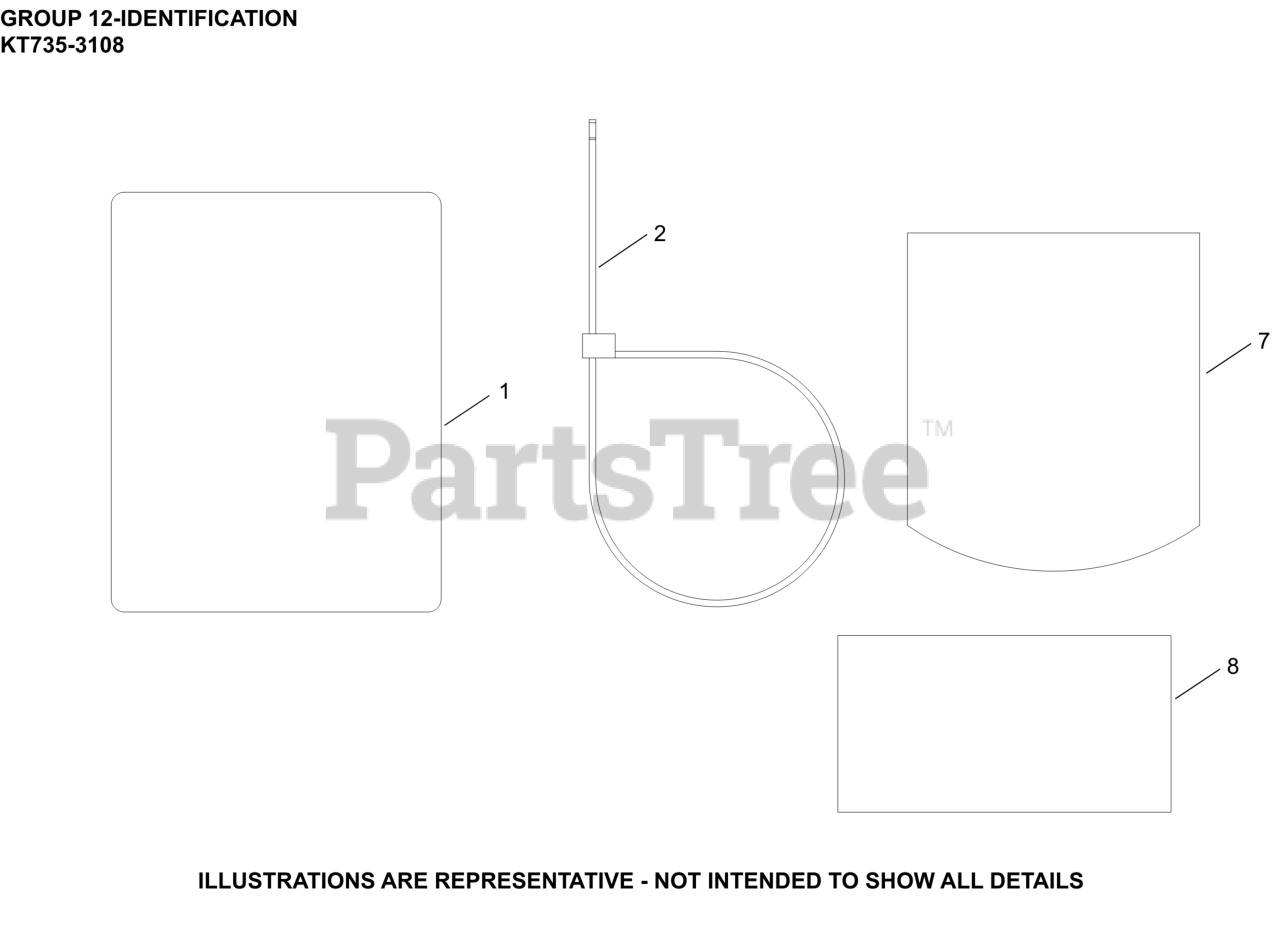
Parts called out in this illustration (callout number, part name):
1	LABEL, CLEAR LAMINATION
7	LABEL, 7000 SERIES KT735 (24 HP,PRO A/F)
8	DECAL, USA
